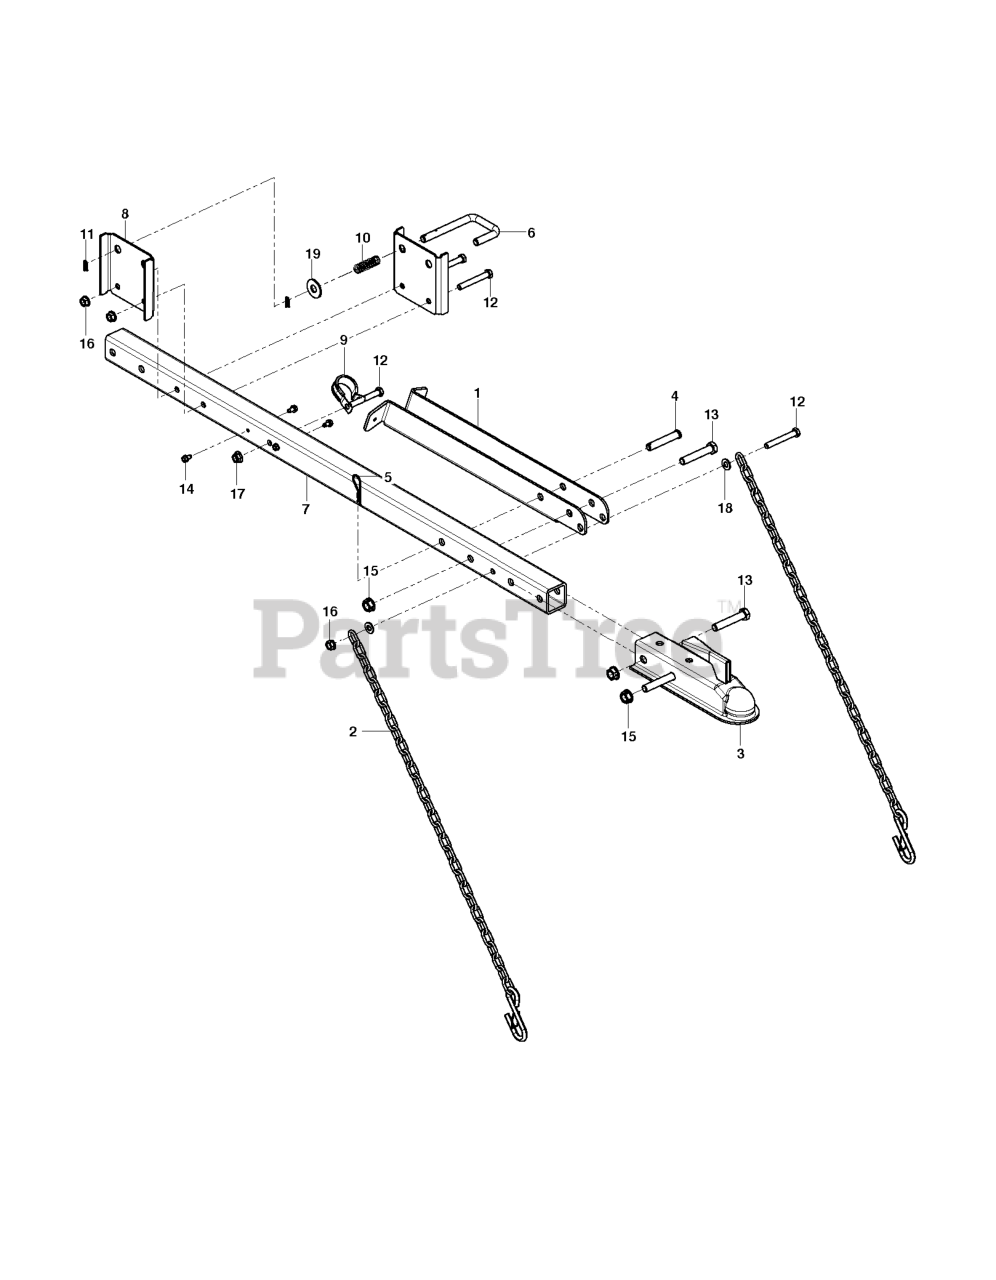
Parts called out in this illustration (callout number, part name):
1	SUPPORT LEG SUPPORT FRONT
2	CHAIN CHAIN, SAFETY 3/16"-30LI
3	HITCH HITCH, BALL-2"
4	PIN PIN, CLEVIS .50 X 3.00 YWZ
5	PIN HAIRPIN, #7 CLIP .094X2.31
6	LOCK LOCK, BEAM
7	DRAWBAR DRAWBAR, TUBE GRAY
8	GUIDE GUIDE, LOCK DOWN
9	CLAMP CLAMP, CUSHIONED STEEL
10	SPRING SPRING, COMP .058X.65X2
12	BOLT BOLT HEX .38-16X3.00 GR5
13	BOLT BOLT HEX .50-13 X 3.00 GR
16	NUT NUT, LK-TOP-FLG .38-16 YWZ
19	WASHER WASHER, FL-STL.563X1.38
